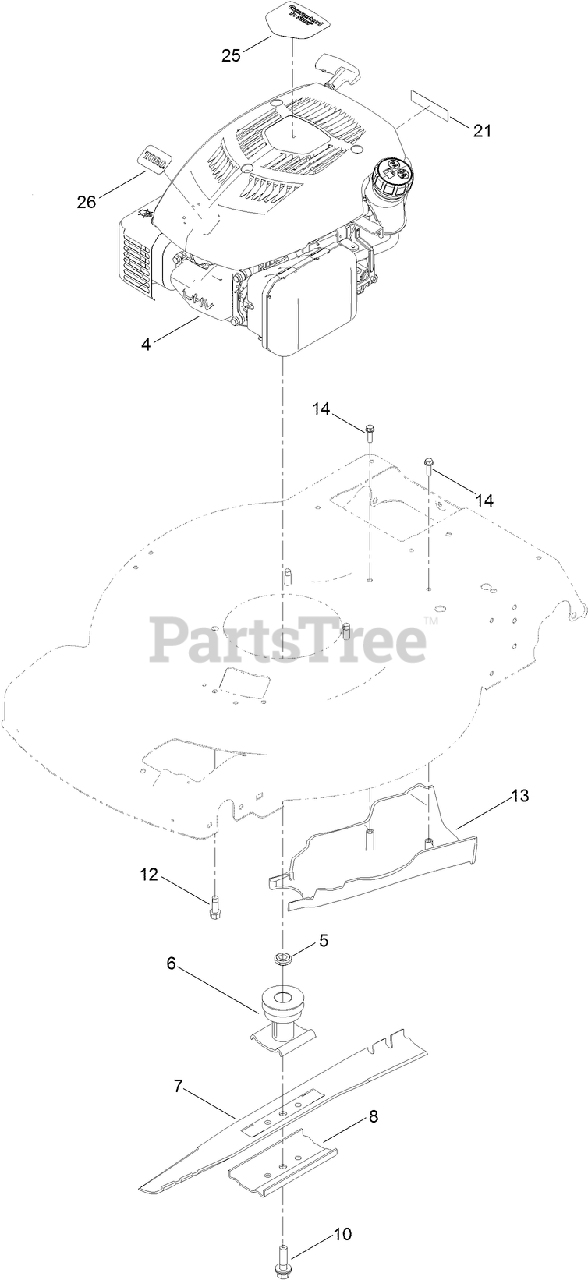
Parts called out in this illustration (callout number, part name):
4	ENGINE-1P65F-2
5	SPACER-DRIVER
6	DRIVER-BLADE
7	BLADE-22 INCH
8	SUPPORT-BLADE
10	BOLT-BLADE
12	SCREW-TAPTITE
13	COVER-BELT, REAR
14	SCREW-HWH
21	DECAL-ARRESTER, SPARK
25	DECAL-ENGINE
